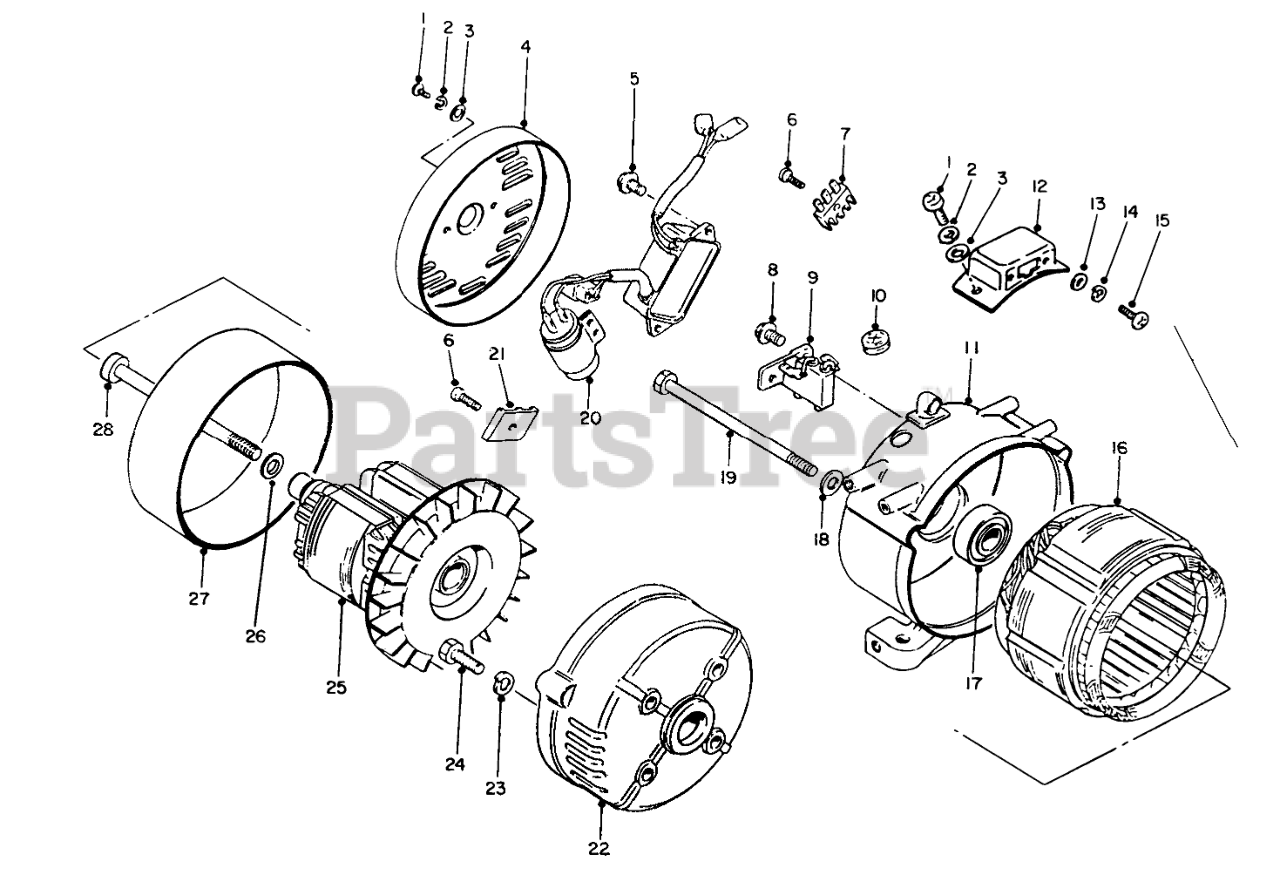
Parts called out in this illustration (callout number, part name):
1	SCREW
2	Washer
3	WASHER
4	REAR COVER
5	Bolt
6	Screw
7	Diode
9	HOLDER
10	Grommet
11	Bracket-Rear
12	Cover-Coupler
13	Washer
14	Lockwasher
15	SCREW
16	Stator (120V)
17	Bearing
18	LOCKWASHER
20	Regulator-Voltage
21	Terminal
22	Bracket-Front
23	Lockwasher
25	Rotor
26	Washer
27	Generator Assembly (Incl. Ref. #1-26 & 28)
